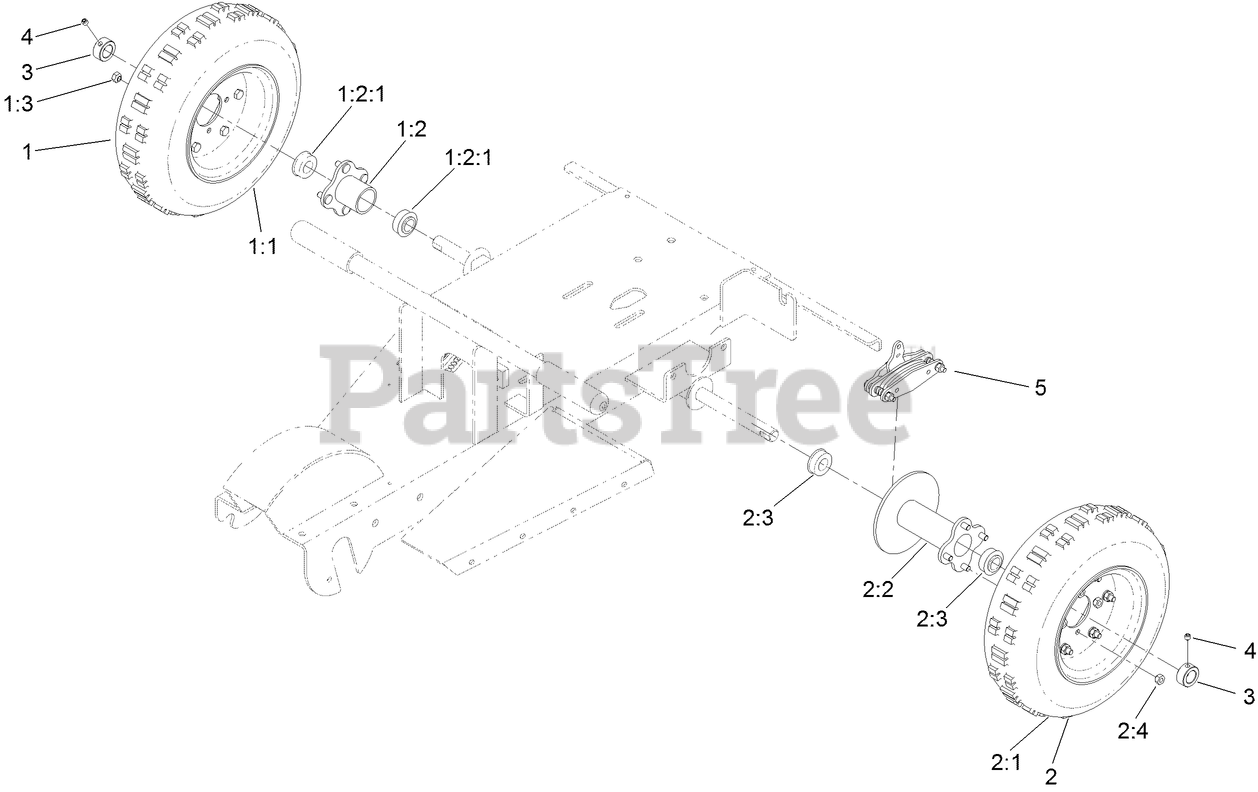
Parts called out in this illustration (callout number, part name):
1	TIRE ASM (W/ HUB)
1:1	TIRE ASM
1:2:1	BEARING-WHEEL
1:3	NUT-WHEEL
2	TIRE ASM (W/ HUB AND BRAKE)
2:1	TIRE ASM
2:3	BEARING-WHEEL
2:4	NUT-WHEEL
3	COLLAR-SET
4	SCREW-SET, HSH
5	BRAKE-CALIPER
